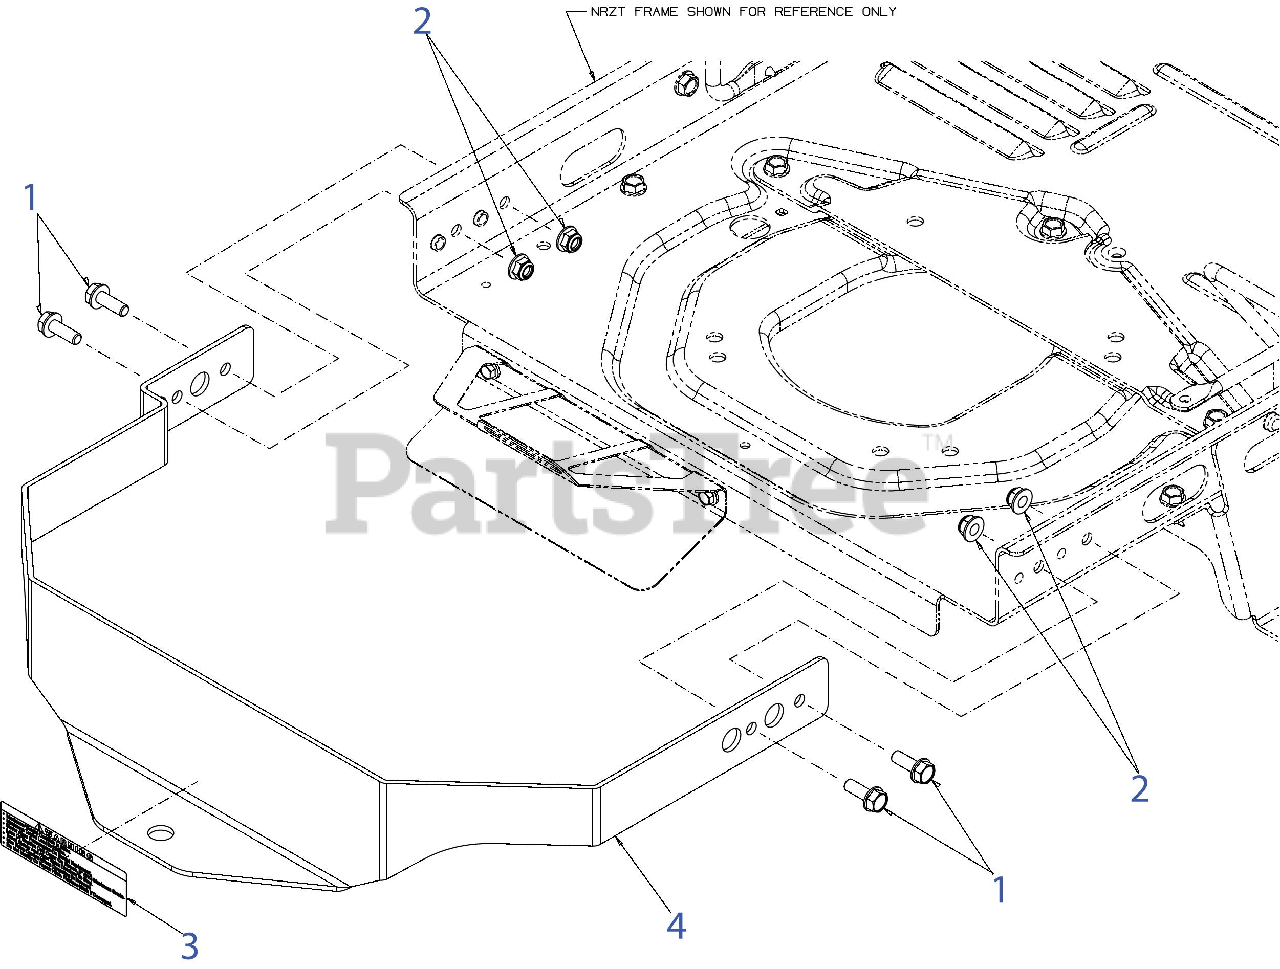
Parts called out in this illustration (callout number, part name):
1	SCREW 5/16-18 x .875 GR5
2	FLANGE LOCK NUT 5/16-18
3	LABEL-TOWING WARNING
4	HITCH BRACKET
